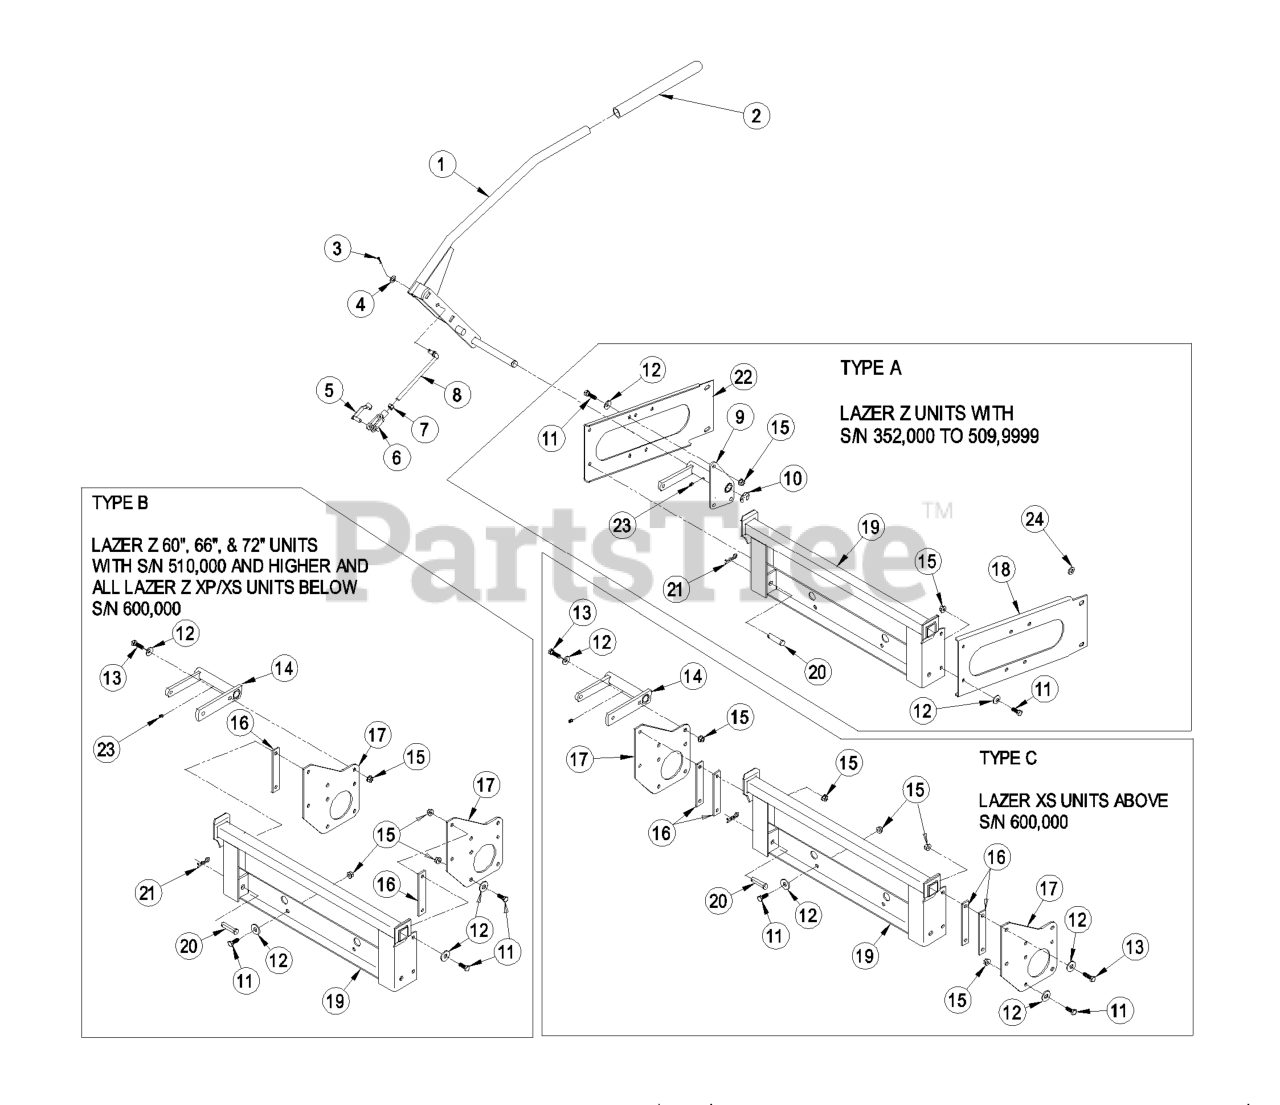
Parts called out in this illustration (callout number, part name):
1	HANDLE AND GRIP ASM
2	GRIP-HANDLE
3	PIN-COTTER
4	WASHER-FLAT
5	PIN-SPRING, CLEVIS
6	YOKE-LINKAGE, BRAKE
7	NUT-HEX
8	LINK-HANDLE
9	WLD, HANDLE MOUNT
11	SCREW-HH
12	WASHER-BELLEVILLE
13	SCREW-HH
14	WLD, HANDLE MOUNT - XP
15	NUT-HHF, WHIZ
16	SPACER
17	PLATE-MOUNT, BAGGER
18	BRACKET-FRAME, RH
19	MOUNT-BAGGER
20	PIN-CLEVIS
21	PIN-COTTER
22	BRACKET-FRAME, LH
23	FITTING-GREASE
24	SPACER
